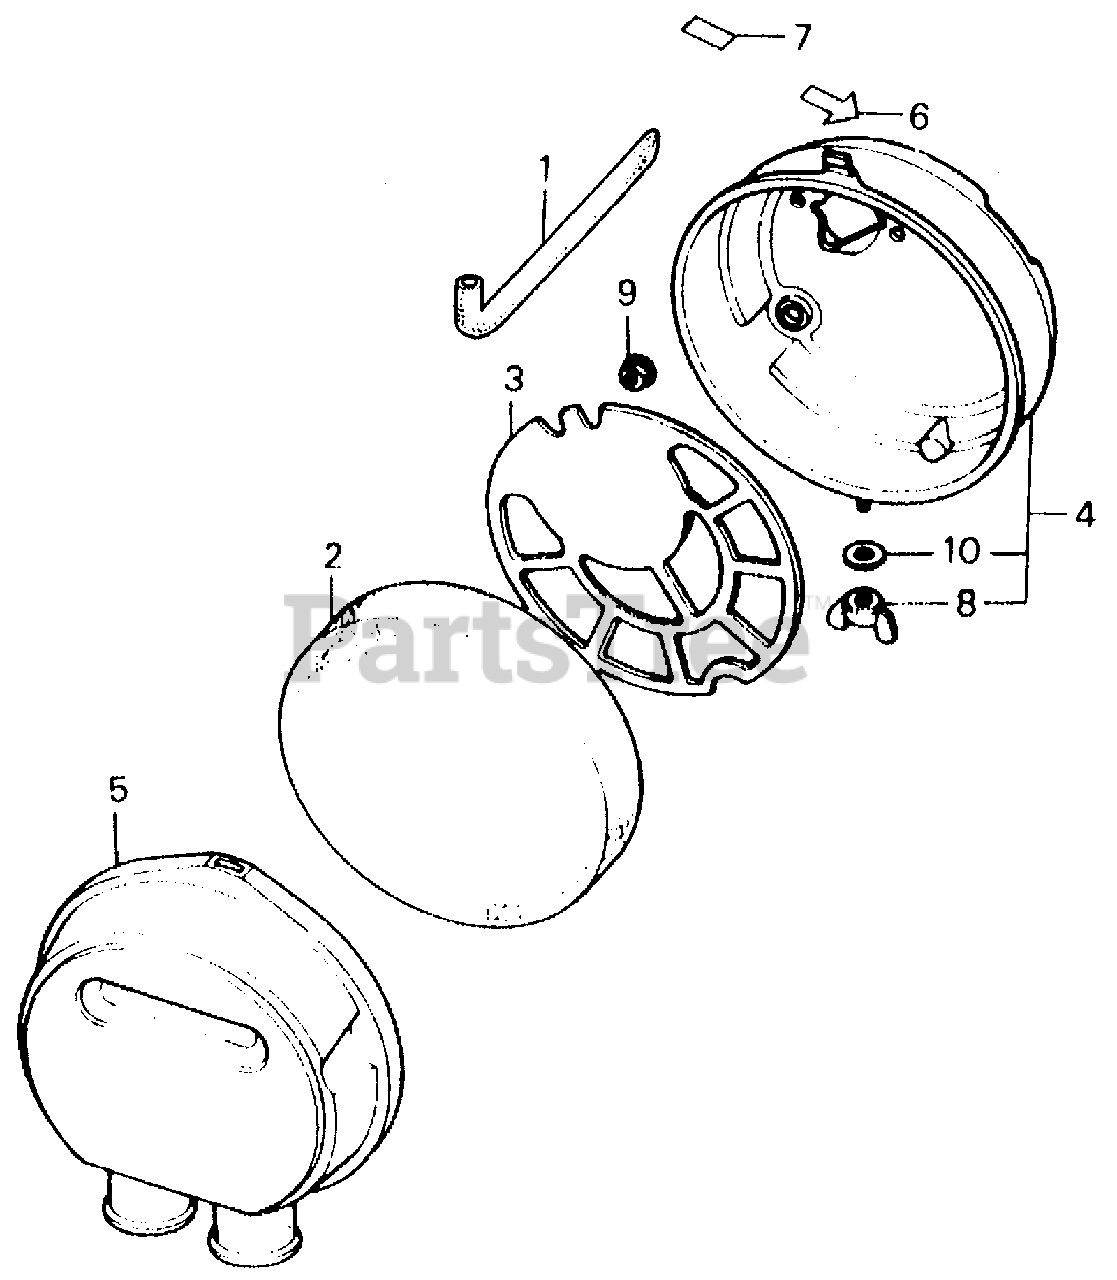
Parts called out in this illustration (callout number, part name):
1	TUBE, BREATHER
2	ELEMENT, AIR CLEANER
3	GRID, AIR CLEANER
4	HOUSING, AIR CLEANER
5	COVER, AIR CLEANER
6	MARK, CHOKE
7	MARK, CHOKE
8	WINGNUT, TOOL BOX SETTING
9	NUT, FLANGE (6MM)
10	WASHER, PLAIN (6MM)
